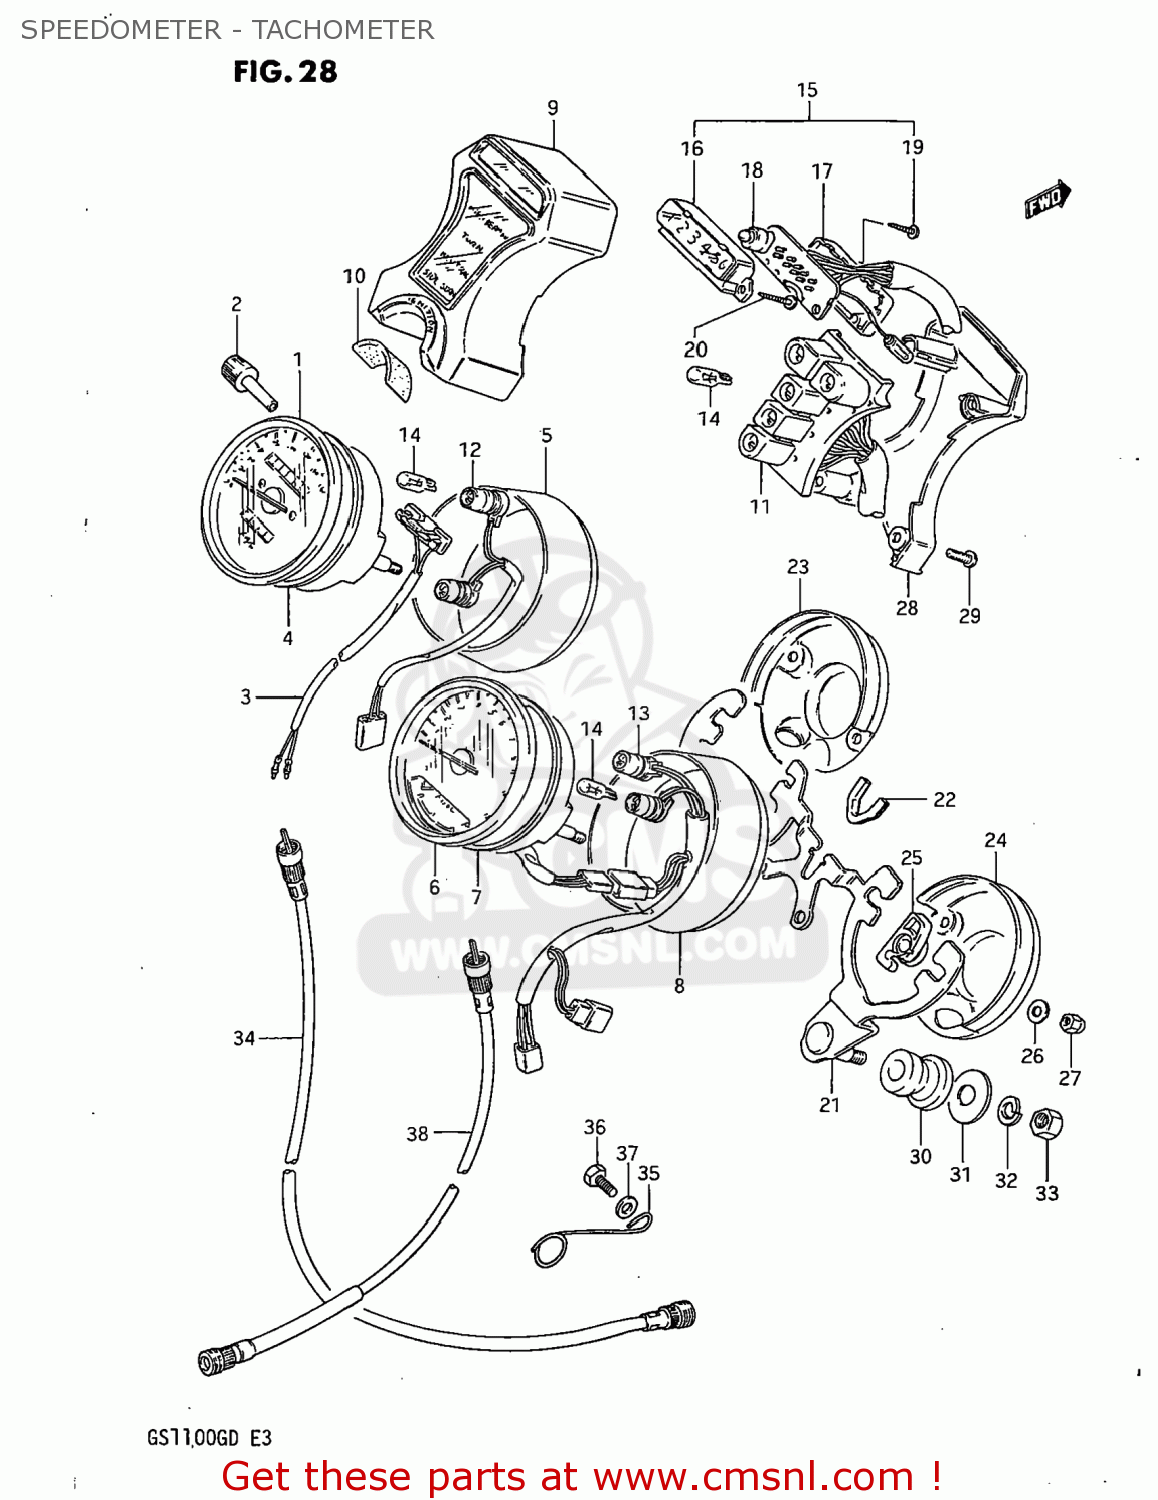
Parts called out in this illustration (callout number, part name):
1	SPEEDOMETER ASSEMBLY
2	KNOB,TRIP
3	WIRE,LEAD
4	CUSHION,METER
5	COVER,SPEEDOMETER
6	TACHOMETER
7	CUSHION,METER
8	COVER,TACHOMETER
9	CASE,PILOT BOX
10	SEAL,IGNITION SWITCH
11	SOCKET,PILOT BOX
12	SOCKET,SPEEDOMETER
13	SOCKET,TACHOMETER
14	BULB(12V3.4W,T10)
15	INDICATOR ASSEMBLY,GEAR POSITION
16	CASE,GEAR INDICATOR
17	COVER,LWR
18	BULB(14V1.12W)
19	SCREW,GEAR INDICATOR
20	SCREW
21	BRACKET,COMBINATION METER
22	BRACKET,COVER
23	COVER,METER,UNDER
24	COVER,TACHOMETER,UNDER
25	CUSHION
26	WASHER
27	NUT
28	COVER,PILOT BOX LWR
29	SCREW,PILOT BULB CASE
30	CUSHION,METER BRACKET
31	WASHER (8.5X20X1.6)
32	LOCK WASHER
33	NUT
34	CABLE ASSEMBLY,SPEEDOMETER
35	CLAMP,SPEEDOMETER CABLE
36	BOLT, UPPER
37	WASHER
38	CABLE ASSEMBLY,TACHOMETER
